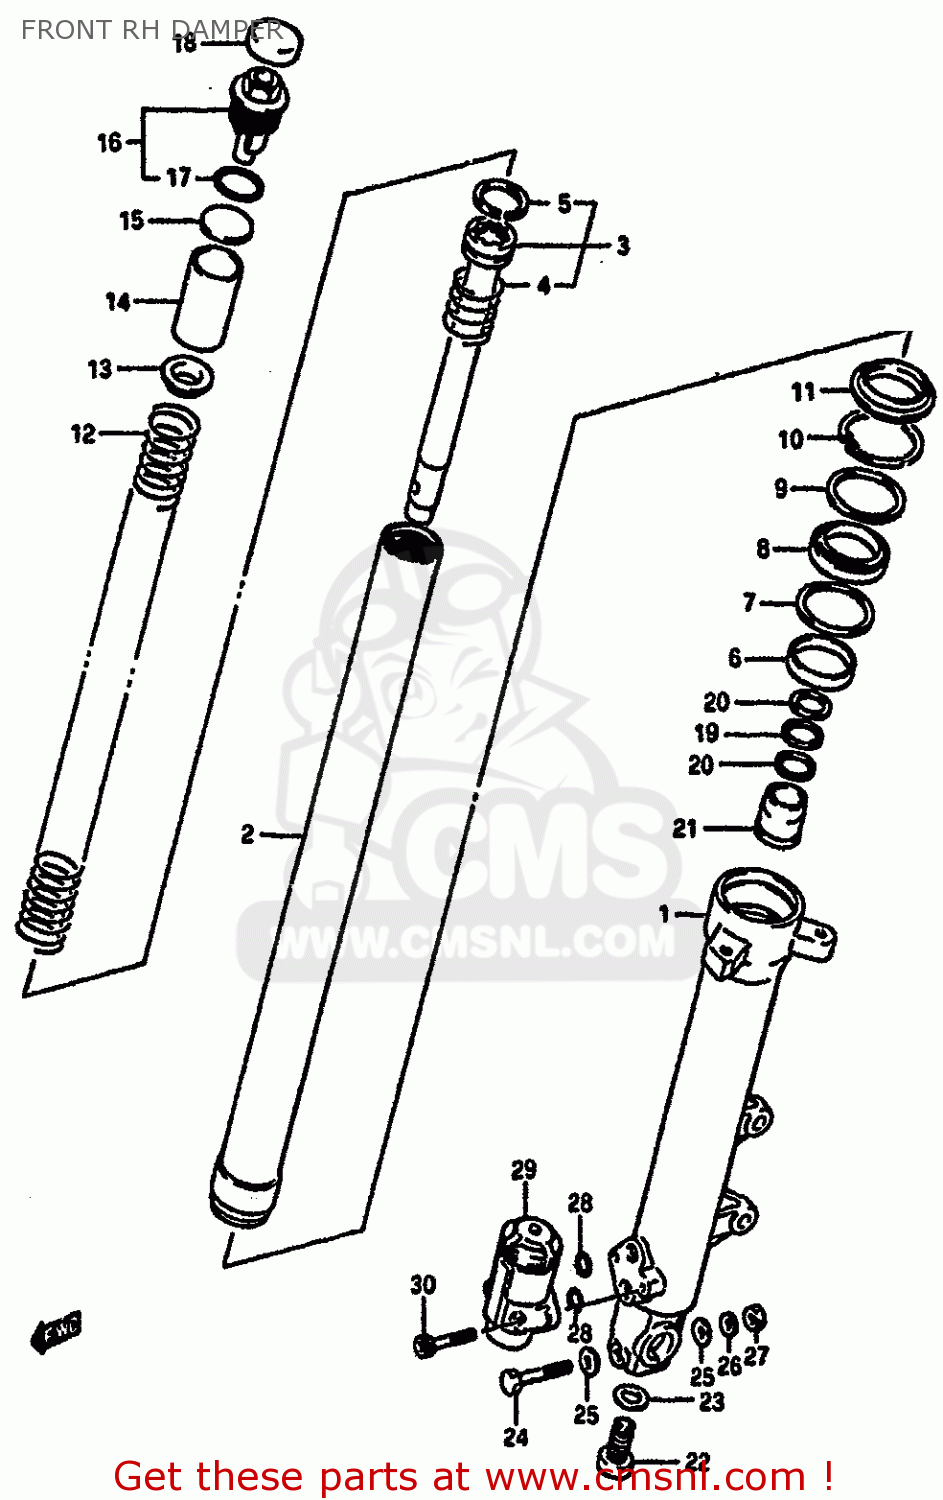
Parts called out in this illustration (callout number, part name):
1	TUBE,OUTER,RIGHT
2	TUBE,FORK INNER
3	CYLINDER,FRONT FORK
4	SPRING,FORK REBOUND
5	RING,FR FORK PISTON
6	METAL,SLIDE
7	WASHER,FORK OIL SEAL
8	OIL SEAL,FRONT FORK
9	WASHER,FORK OIL SEAL
10	RING,OIL SEAL STOPPER
11	DUST SEAL,FRONT FORK
12	SPRING,FRONT FORK
13	WASHER
14	SPACER
15	WASHER,FR FORK SPRING
16	CAP,FORK INNER TUBE
17	O RING
18	CAP,FORK INNER TUBE
19	WASHER,OIL LOCK PIECE
20	SPRING,FORK OIL LOCK PIECE
21	PIECE,OIL LOCK
22	BOLT(14X25)
23	GASKET (NAS)
24	BOLT 8X55
25	WASHER
26	WASHER,LOCK,8.
27	NUT
28	O RING
29	PDF ASSEMBLY
30	BOLT
